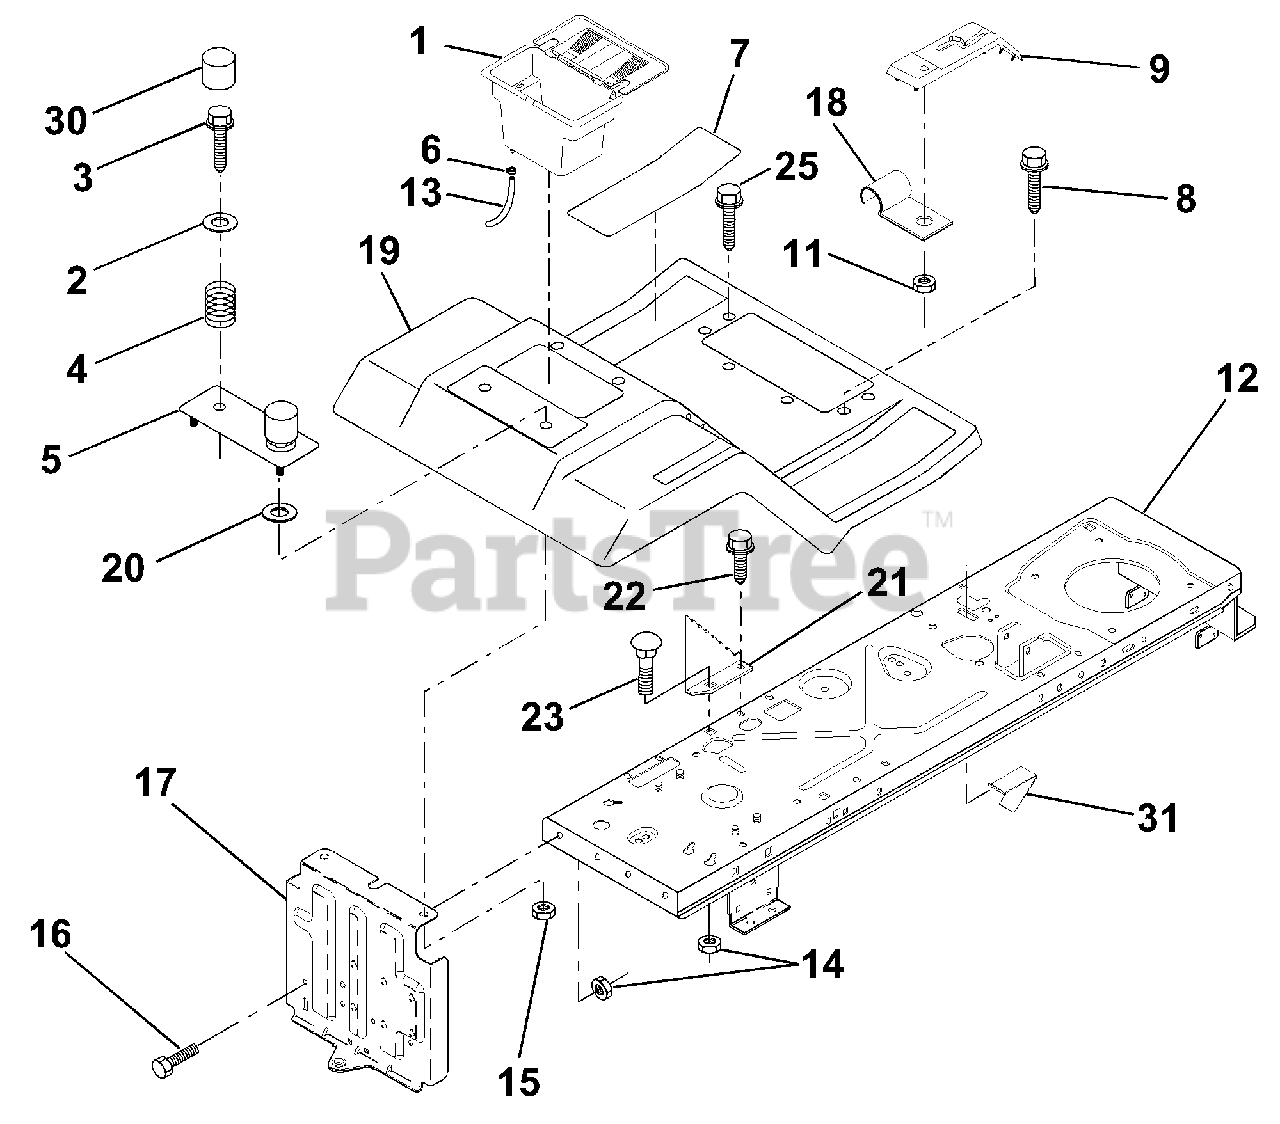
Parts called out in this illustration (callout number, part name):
1	Case Asm. Battery
2	Washer 13/32 x 1-1/4 x 12 Ga.
3	Screw Thdrol. 3/8-16 x 3/4
4	Spring seat
5	Plate Asm. Pnt Battery Fender
6	Clamp Hose Olive
7	Pad Footrest Rubber Deluxe
8	Screw Thdrol. 5/16-18 x 3/4
9	Console Shf. 6sp W/Ign.
11	Nut Self Thd. Wsh-Hd 1/4
12	Chassis Asm. Weldment
13	Tube Plastic
14	Nut Lock Hex W/Ins 5/16-18 UNC
15	Nut Keps Hex 1/4-20
16	Bolt Hex Hd. 5/16-18 x 3/4
17	Drawbar Asm.
18	Clip Insulated
19	Fend/Foot Asm. Pnt Shf. Fnd.
20	Washer 9/32 x 7/8 x 13 Ga.
21	Bracket Stop Depth
22	Screw Thdrol 5/16-18 x 1/2
23	Bolt Rdhdsqnk. 5/16-18 x 3/4
25	Scr-Hex Wsh Rol 5/16-18 x 1
30	Cap Spring
31	Switch Actuator
